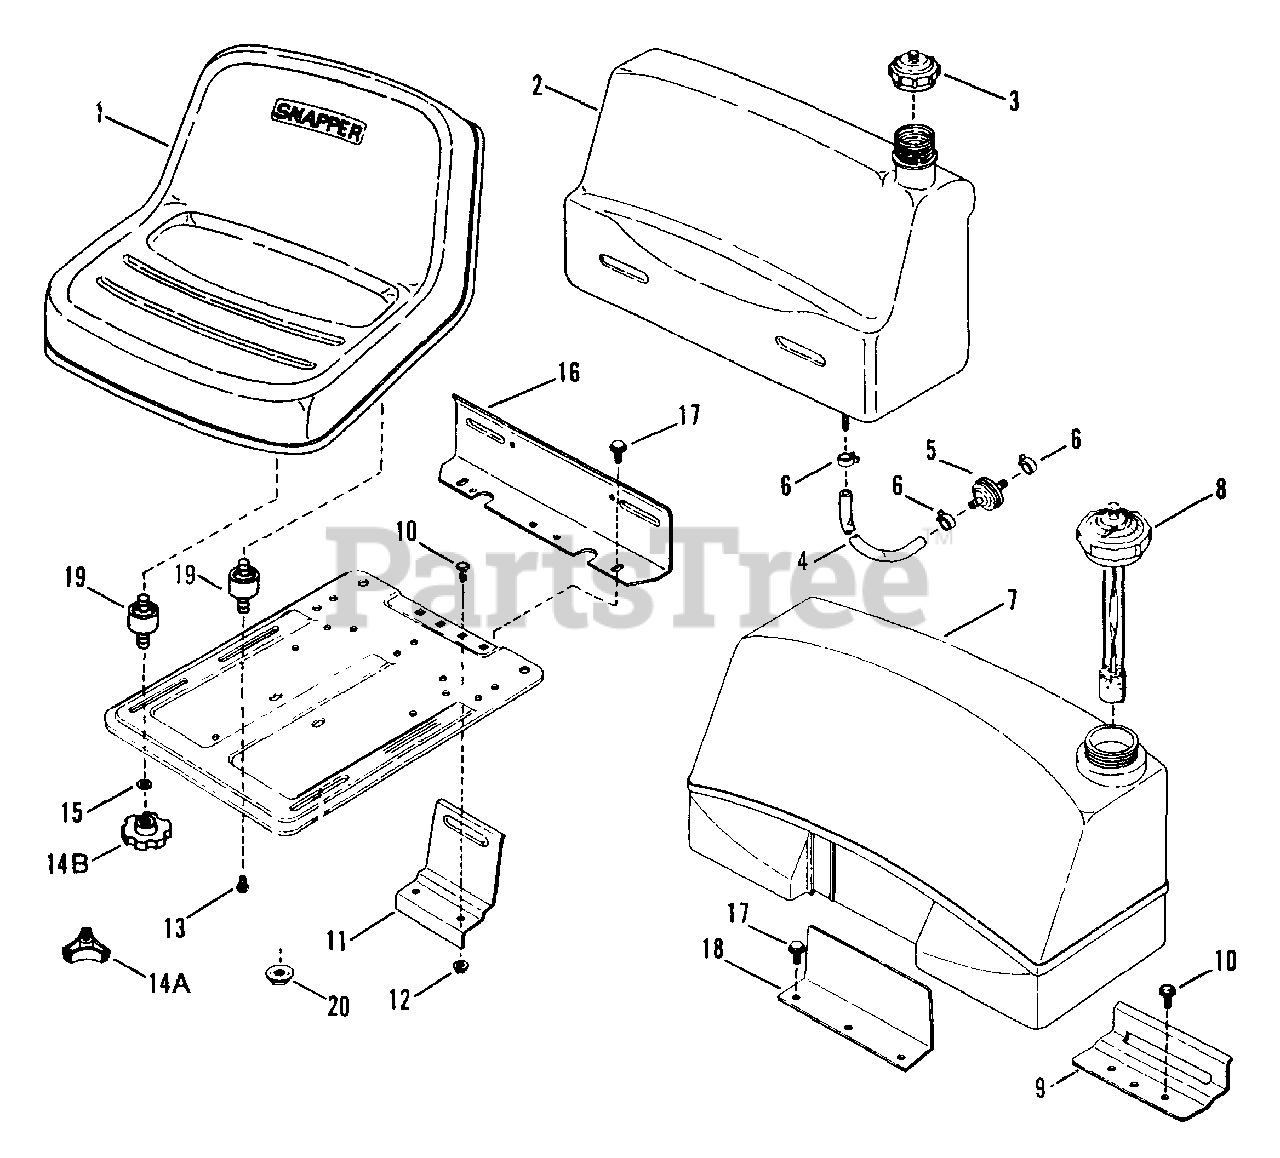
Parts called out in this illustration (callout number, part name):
1	SEAT, Low Back
2	ASSEMBLY, Fuel Tank
3	CAP, Fuel Tank
4	HOSE, Fuel, 7" Long
5	FILTER, Fuel, In-Line
6	CLAMP, Fuel Line
7	ASSEMBLY, Fuel Tank
8	CAP & GAUGE, Fuel Tank
9	BRACKET, Fuel Tank, Rear
10	BOLT, 5/16 - 18 x 5/8" Short Neck Carriage
11	BRACKET, Fuel Tank, Rear
12	NUT, 5/16 - 18 Hex Flange Lock
13	BOLT, 5/16 - 18 x 1/2" Hex Flange Lock
14A	KNOB, Seat Adjusting
14B	KNOB, Seat Adjusting
15	WASHER, 5/16 Flat
16	BRACKET, Fuel Tank, Front
17	SCREW, 5/16 - 18 x 5/8" Self-Tapping
18	BRACKET, Fuel Tank, Front
19	MOUNT, ISO Sandwich
20	NUT, 5/16 - 18 Hex Flange Lock
